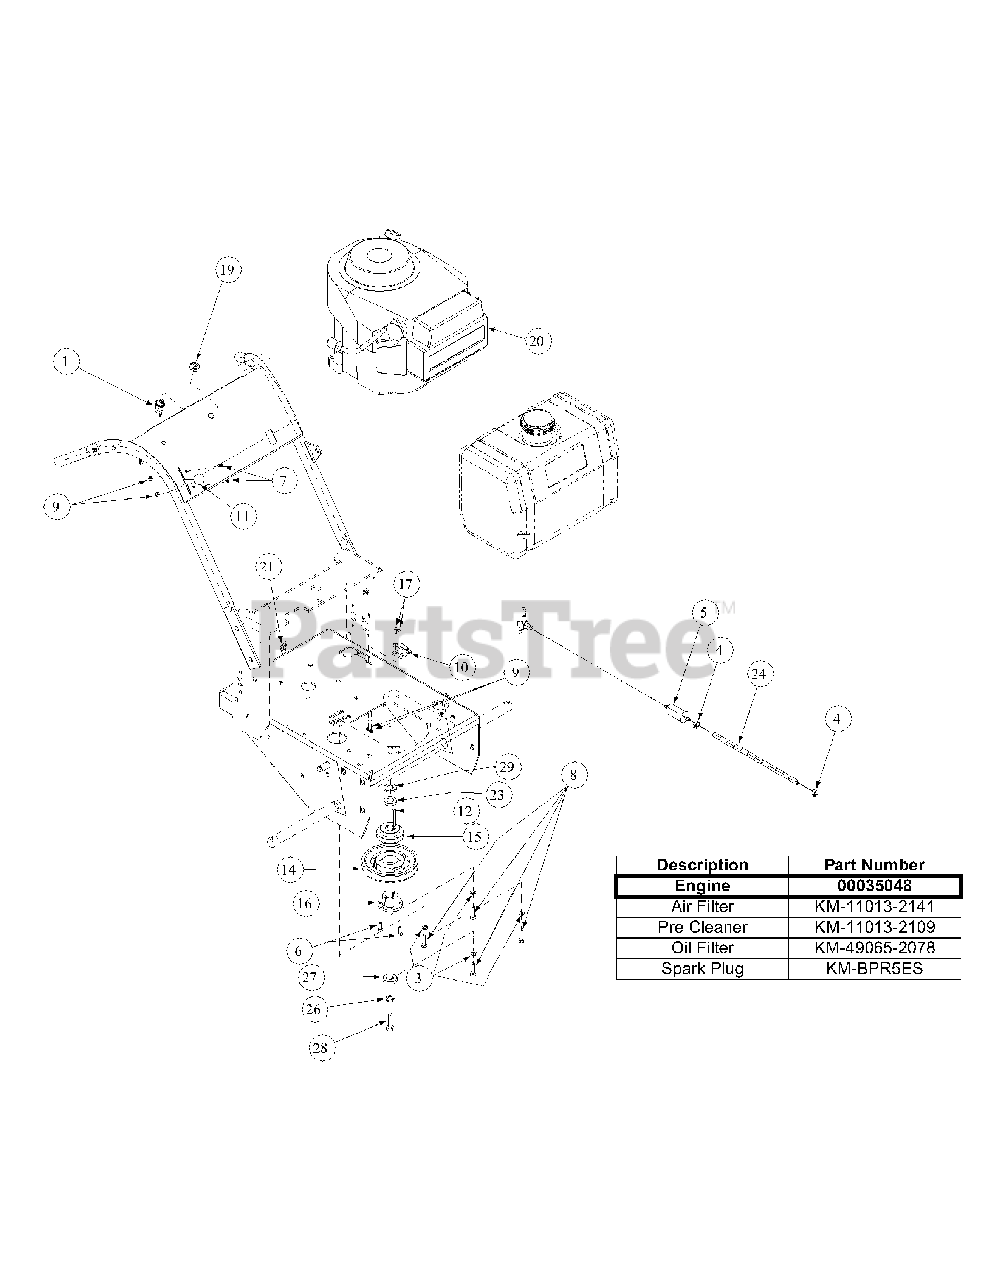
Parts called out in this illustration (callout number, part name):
1	Single Ignition ON/OFF Switch
3	Lock Washer, 5/16
4	Clamp
5	Kohler Fuel Filter
6	Hex Cap Screw, 1/4-20, .75
7	Screw, Hex Washer, 10-32 x 1/2
8	Cap Screw, 1.25 x 30
9	Lock Nut, Nylon Insert, 10-32
10	Delta Switch
11	Control Throttle w/Detent, 39.2
12	Key Stick, 1/4 x 1/4 x 2-3/4
14	Deck Pulley
15	Traction Pulley
17	Machine Screw, 10-32 x 5/8
18	Support Clamp Tubing, 1/2"
19	Nut w/cap, 5/8-32 Ignition
20	14 HP Kawasaki Engine
21	Support Clamp, 3/8 OD
23	Flat Washer
24	12" Fuel Hose x .25 ID
26	Lock Washer, 7/16
27	Clutch Washer
28	Hex Cap Screw, M10 x 1.5, 30mm, GR10.9
29	Spacer, Engine Pulley
